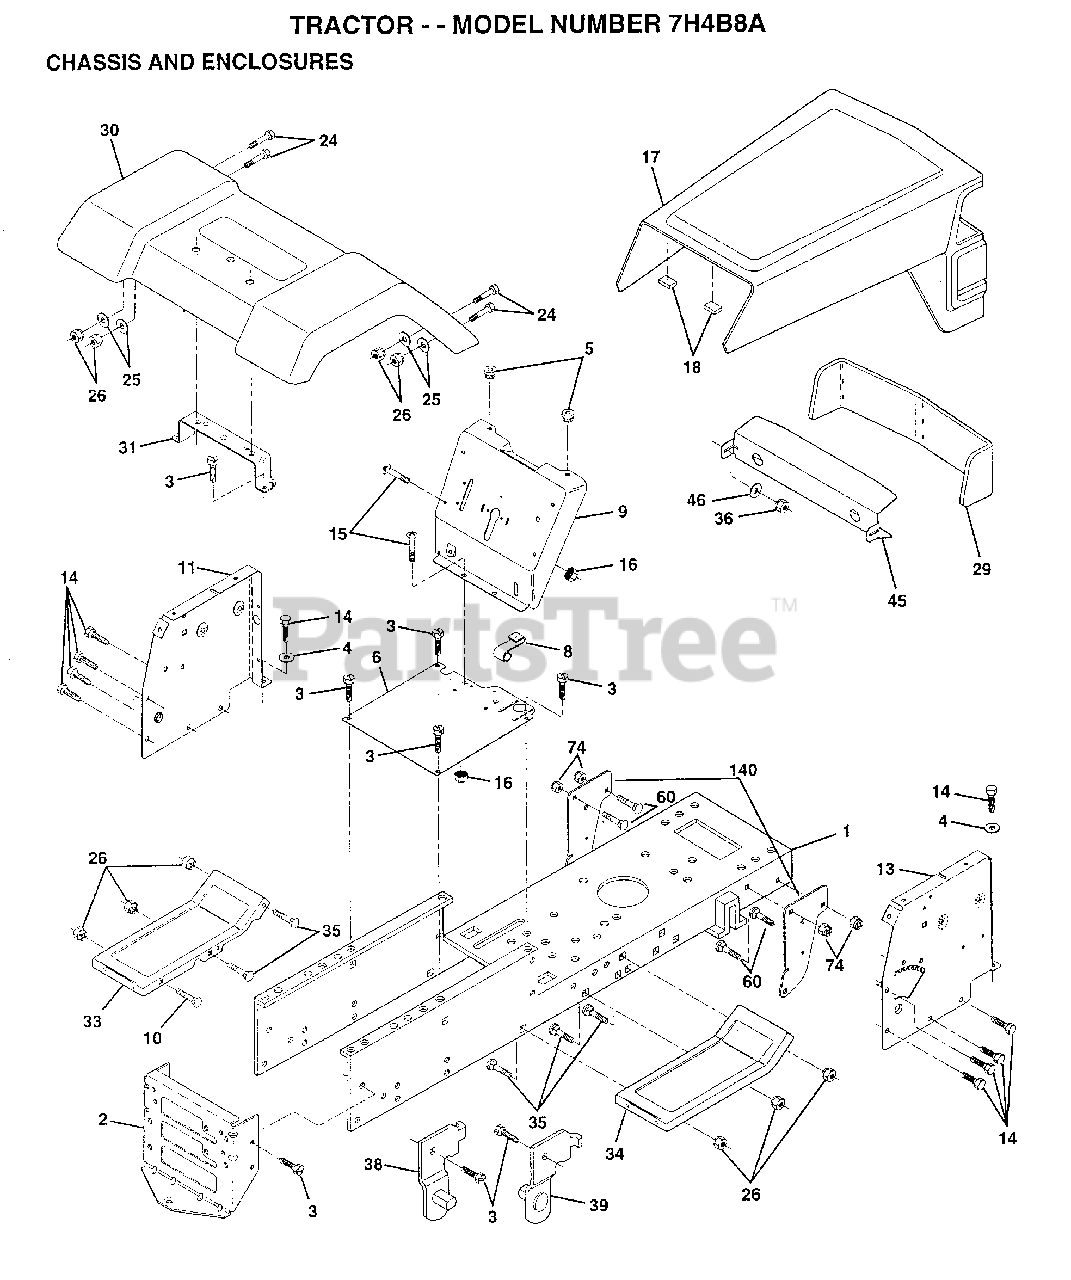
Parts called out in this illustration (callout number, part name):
1	CHASSIS WLDMT 11G
3	SCREW
4	WASHER
8	"CLIP,INSULATOR"
9	DASH.SLKSC.LT.1PC
11	PANEL.DASH.LH.
14	SCREW LT
15	SCREW
17	HOOD/GRILL ASM
24	BOLT
25	WASHER
26	NUT
31	BRKT FENDER
33	FOOTREST LH
34	FOOTREST RH
35	BOLT
36	PAL NUT LT
38	BRACKET ASM LH
39	BRACKET ASM RH
46	RETAINER
60	BOLT
